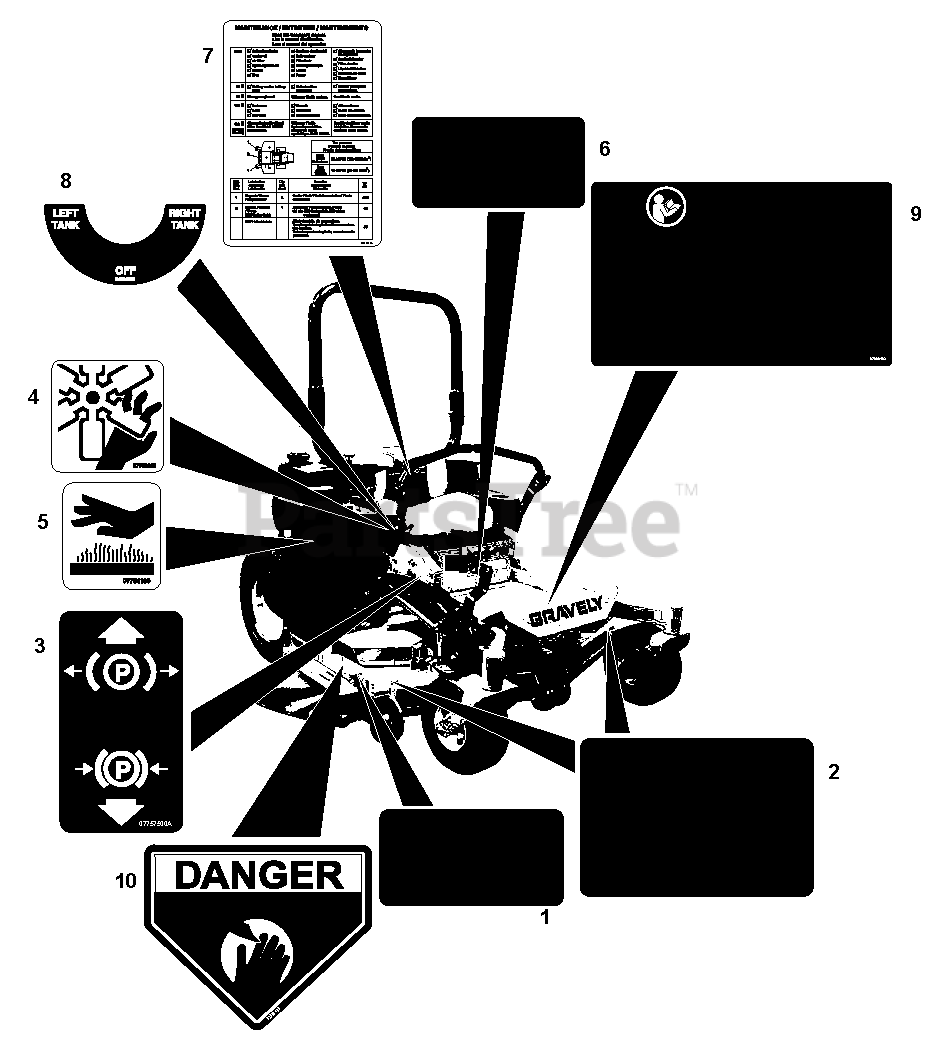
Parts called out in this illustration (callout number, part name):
1	Decal, Safety Deck Guarding
2	Decal, Safety Mower Deck
3	Decal, Parking Brake Lever
4	Decal, Danger Fan
5	Decal, Hot Surface
6	Decal, Safety Guarding
7	Decal, Maintenance Instructions
8	Decal, Fuel Control Valve
9	Decal, Main Safety Commercial
10	Decal, Danger
